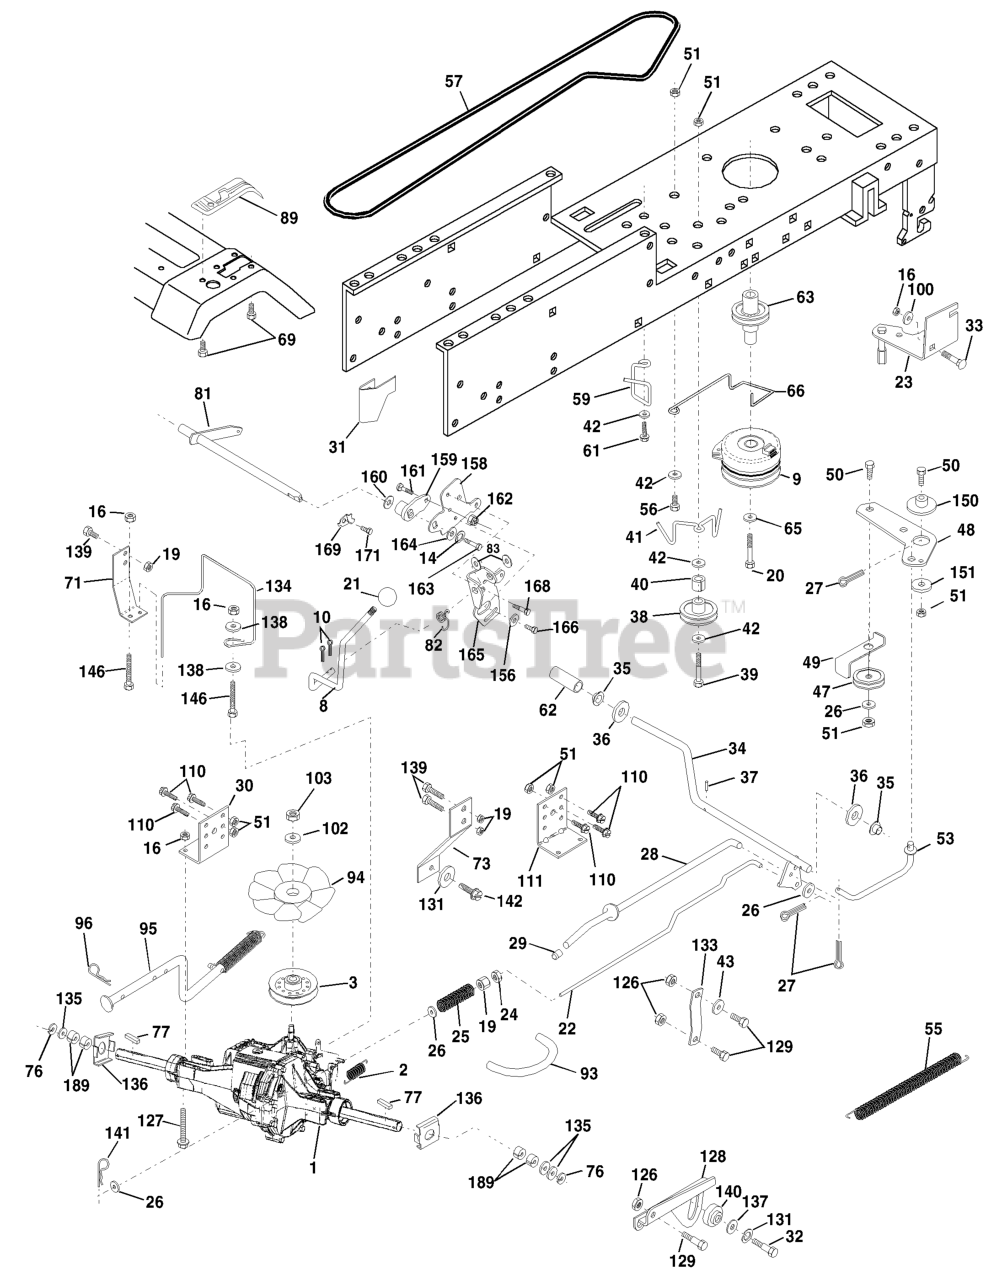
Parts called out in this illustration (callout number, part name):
2	SPRING BRAKE
3	PULLEY, TRANSAXLE
8	ROD SHIFT FENDER
9	ELECTRIC CLUTCH
10	PIN COTTER
14	LOCKWASHER
16	NUT.71038.31-18.HEX.NYLOCK
19	NUT
20	BOLT HEX
21	KNOB.DELUXE.(PISTOL.GRIP).BLAC
23	BRACKET, ASM CLUTCH MTG
24	NUT
25	SPRING ROD LT
26	WASHER
27	COTTER PIN
28	ROD BRAKE PARK LT
29	PLUNGER CAP
30	BRKT TRANS LH
31	KEEPER BELT LH
32	BOLT
33	RP BOLT 5/16-18 X3/4 ZN/YEL GR
34	SHAFT, FOOT PEDAL
35	BEARING.NYLON
36	WASHER LT
37	DRIVE PIN
38	FLAT IDLER PULLEY
41	KEEPER.BELT.IDLER.FLAT
42	WASHER
43	WASHER T
47	IDLER PULLEY
48	BELLCRANK, CLUTCH
49	RETAIN BELT
50	BOLT
53	LINK, CLUTCH LT
55	SPRING, RETURN LT
59	KEEPER CENTER SPAN
61	SCREW
62	COVER, PEDAL (1 2)
63	PULLEY, CLUTCH ELECT EVX
65	LOCKWASHER
66	BELT KEEPER
69	SCREW.HI-LO.CONSOLE
71	STRAP.TORQUE.LH.HYDRO
73	STRAP.TORQUE.RH.HYDRO
74	WASHER, SPACER AXLE
76	E RING HYT
77	SQ KEY STD
81	SHIFT.ASM.CROSS.TAPER
82	SPRING,TORSION
83	WASHER
89	FENDER CONSOLE
93	LINE FUEL HYD 4"
94	FAN 7" HYDRO
95	CONTROL.ASM.BYPASS.HYDRO-3000
96	RETAINER M
100	WASHER M
103	NUT.HEX.1/2-20
111	BRKT TRANS RH
127	BOLT HEX FLGHD 5/16-18X3 GR. 5
129	BOLT, SHOULDER LT
131	LOCKWASHER
133	LINK, TRANSAXLE
134	BELT GUIDE
136	WASHER.AXLE.FLANGE.HG-3000
138	Washer 11/32 x 1.25 x 16 Ja.
142	Bolt 5/16 x 24 x 1
146	Bolt Hex Flghd 5/16-18 x 2-1/4
150	BUSHING.BELLCRANK.GRD.DR
151	WASHER 12/32X2X10GA
156	WASHER.SRRTD.5/16
158	BRACKET
159	HUB
160	Washer 29/32 x 1-1/4 x 16 Ga
161	BOLT
162	NUT.CROWNLOCK.1/4
163	BOLT
164	Washer 5/8 x .281 x 10 Ga
165	RP BRACKET
168	BOLT.SHOULDER.5/16-18X
169	PLATE FASTENING LT
171	SCREW LT
